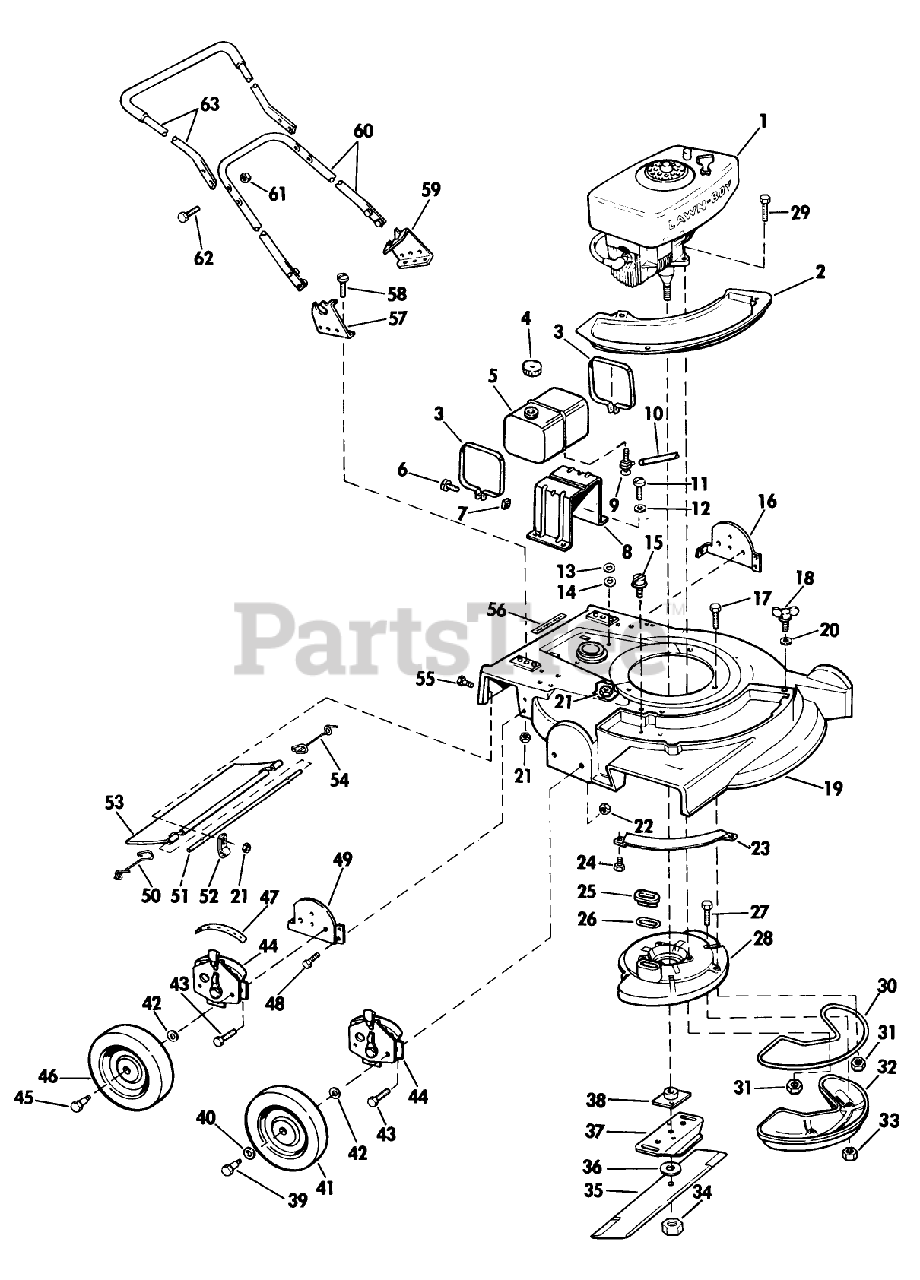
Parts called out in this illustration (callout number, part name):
7	Nut
9	VALVE&SCREEN SM
11	BOLT PIONEER
14	WASHER
17	SCREW
18	WING SCREW LAWRE
22	NUT
23	BAR-TOE
25	SLEEVE
26	GASKET S
31	NUT-LOCK F
34	NUT-BLADE
36	WASHER
38	PLATE AND COLLAR ASM
39	BOLT WHEEL
40	Washer
42	WASHER WROUGHT
45	BOLT-SHOULDER
50	SPRING;TRAILING SHIELD RH
51	ROD 21" ADVANCE
52	CLAMP ROD KMC
54	SPRIG T/SHLD ASOC
58	BOLT RB&W
61	STOP NUT
